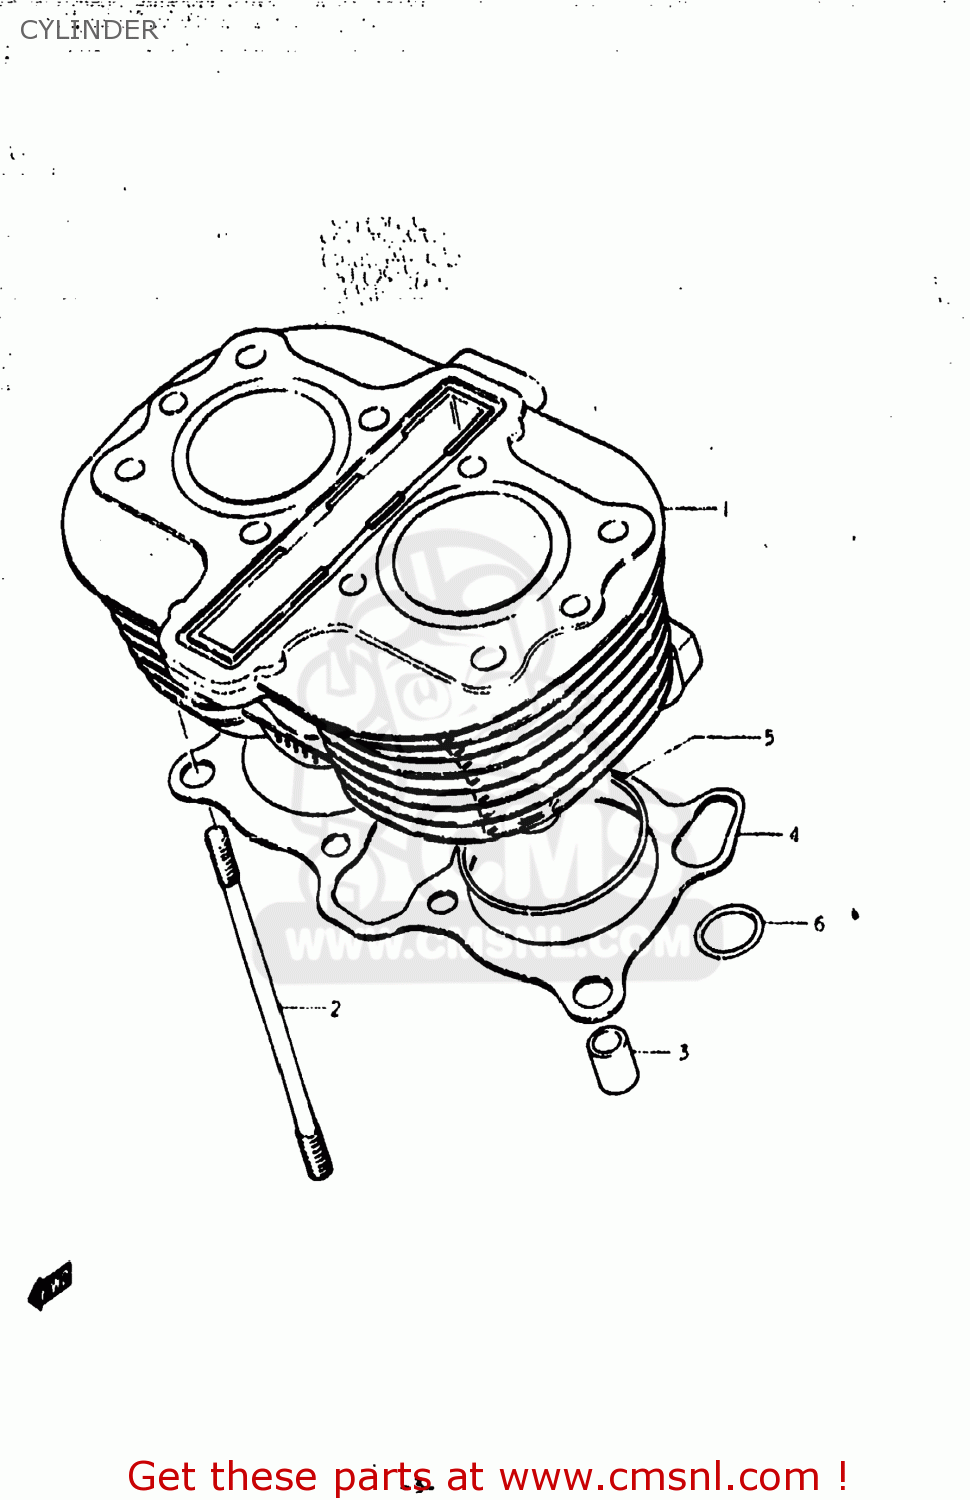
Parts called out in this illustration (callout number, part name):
1	CYLINDER
2	STUD
3	PIN
4	GASKET,CYLINDER (MCA)
5	O RING(D:2,ID:70)
6	O RING(D:3.05)
